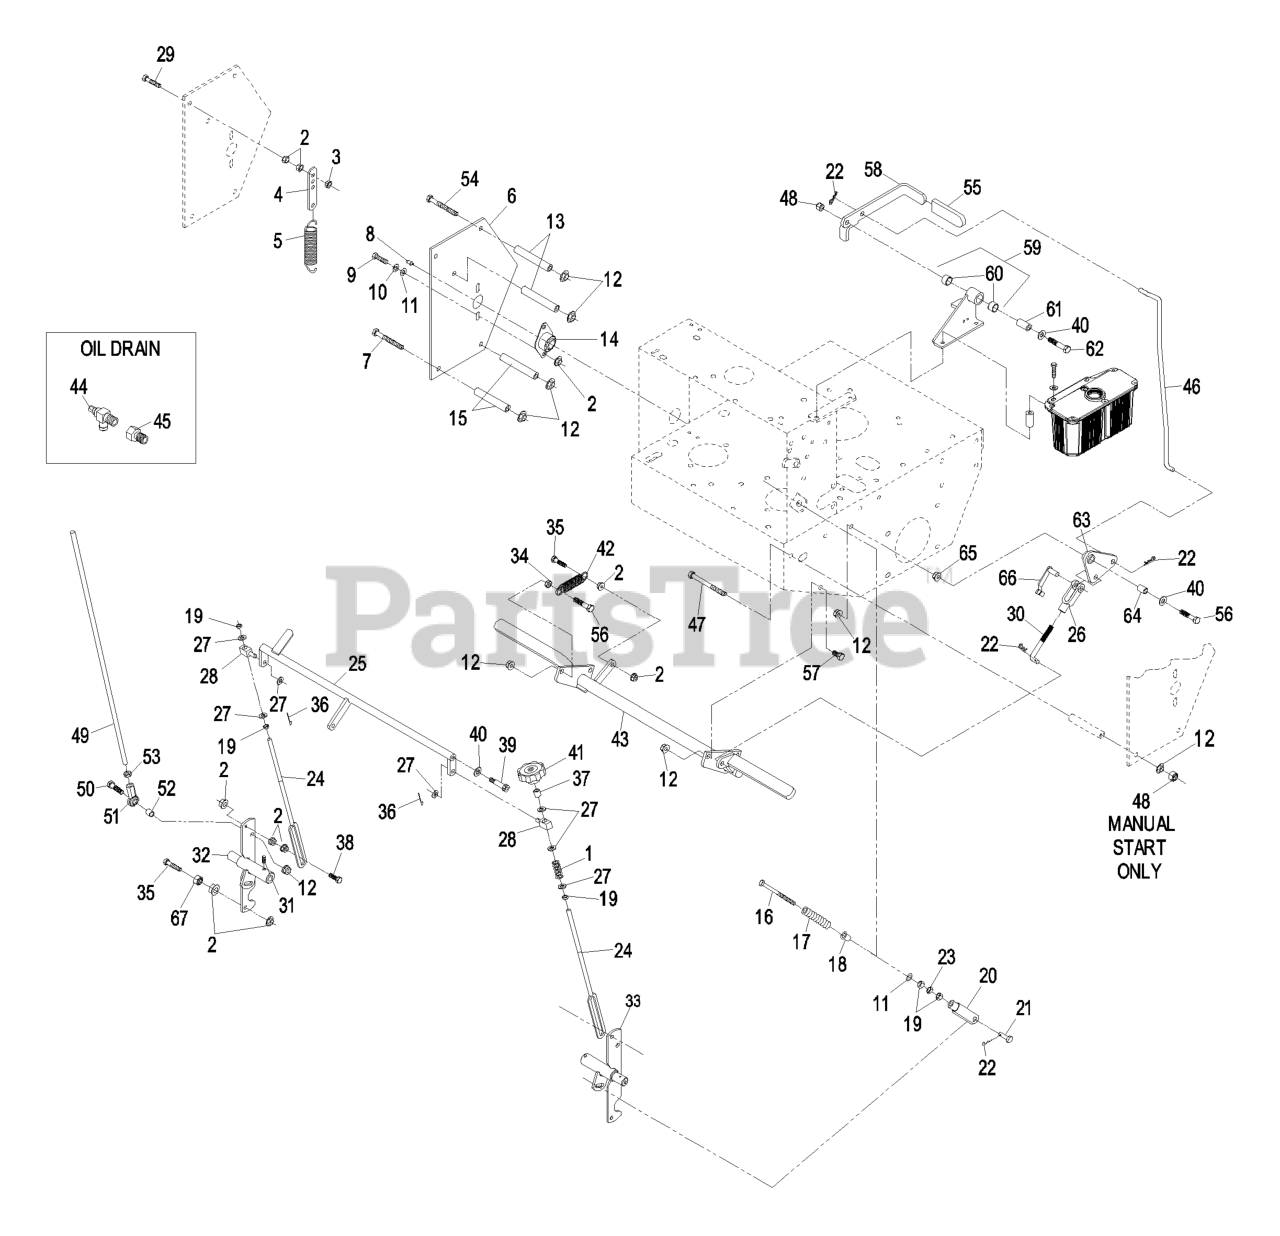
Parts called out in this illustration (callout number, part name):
1	SPRING-COMPRESSION
3	NUT-LOCK, NI
4	TAB-SPRING, EXTENSION
5	SPRING-EXTENSION
6	SCREW-HH
7	SCREW-HH
8	FITTING-GREASE
9	SCREW-HH
10	WASHER-LOCK
11	WASHER-FLAT
12	NUT-HHF, WHIZ
13	SPACER-SHIELD
14	BEARING-FLANGE, SIDE
15	SPACER-SHIELD
16	BOLT-RETURN, NEUTRAL
17	SPRING,COMPRESSION (NEUT)
18	BUSHING-FLANGED
19	NUT-HEX
20	YOKE-ADJUSTABLE
21	PIN-CLEVIS
22	PIN-COTTER
23	NUT-JAM
24	LINK-CONTROL, SPEED
25	CRANK-CONTROL, SPEED
26	YOKE-LINKAGE, BRAKE
27	WASHER-PLAIN
29	BOLT-TAP, HH
30	LINKAGE-LOWER
31	SCREW-SET
32	SHAFT-CONTROL, LH
33	SHAFT-CONTROL, RH
34	NUT-JAM
35	SCREW-HH
36	PIN-COTTER
38	SCREW-HH
39	SCREW-HSH
40	WASHER-FLAT
41	KNOB-TRACKING
42	SPRING-IDLER
44	VALVE-DRAIN, OIL
45	ADAPTER
46	LINKAGE,UPPER- TTHP
47	SCREW-HH
48	NUT-LOCK, NI
49	LINK,DRIVE (PLTD)
50	SCREW-HH
51	JOINT-BALL END, LH
52	SPACER-TUBE, PUMP LINK
53	NUT-HEX JAM, LH
54	SCREW-HH
55	GRIP-LEVER
56	SCREW-HH
57	SCREW-HH
58	LEVER,PARK BRK W/DECAL
59	BRACKET ASM
60	SLEEVE-BUSHING
61	BUSHING-PIVOT
62	SCREW-HH
63	BELLCRANK ASM
64	BUSHING-PLASTIC
66	PIN-SPRING, CLEVIS
67	NUT-JAM
